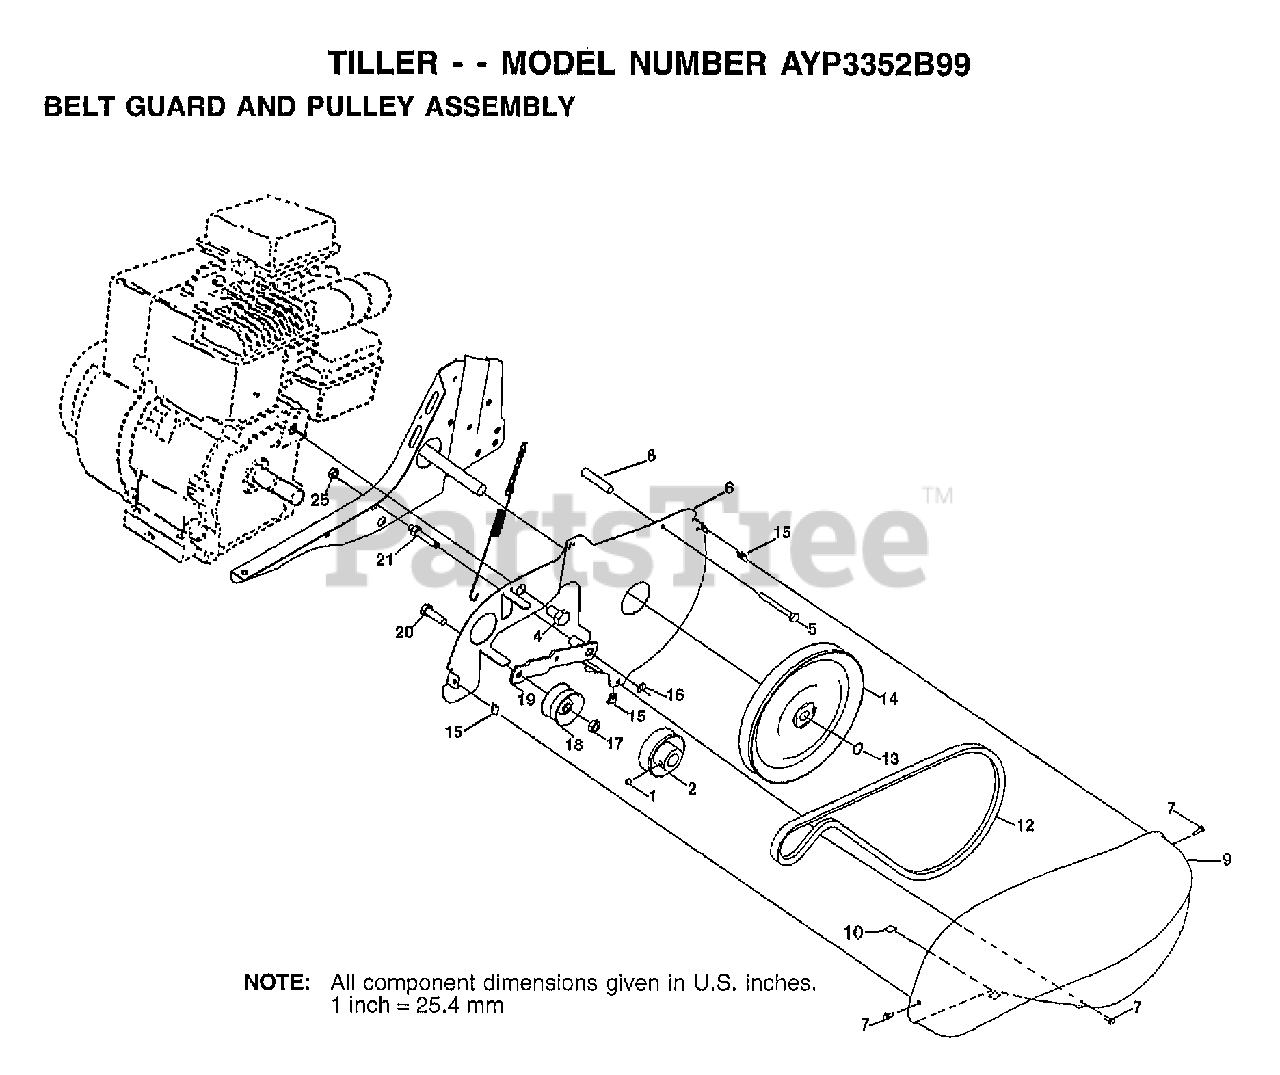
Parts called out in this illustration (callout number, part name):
1	SET SCREW
2	ENGINE PULLEY
4	BOLT.HEX.HEAD
5	BOLT.ROLLER.1/4-20X2 1/2
6	SHEILD.INNER.GUARD
7	SCREW HX WSH.HD#8-18X1/2
8	SPACER.SPLIT
9	GUARD.PNT.BELT
10	PAD IDLER TI
12	V BELT STD
14	SHEAVE.TRANS
15	NUT J CLIP #8
16	KLIP RING TI
17	NUT
18	"PULLEY,IDLER"
19	"ARM, IDLER"
21	SHAFT IDLER TI
25	JAM NUT TI
